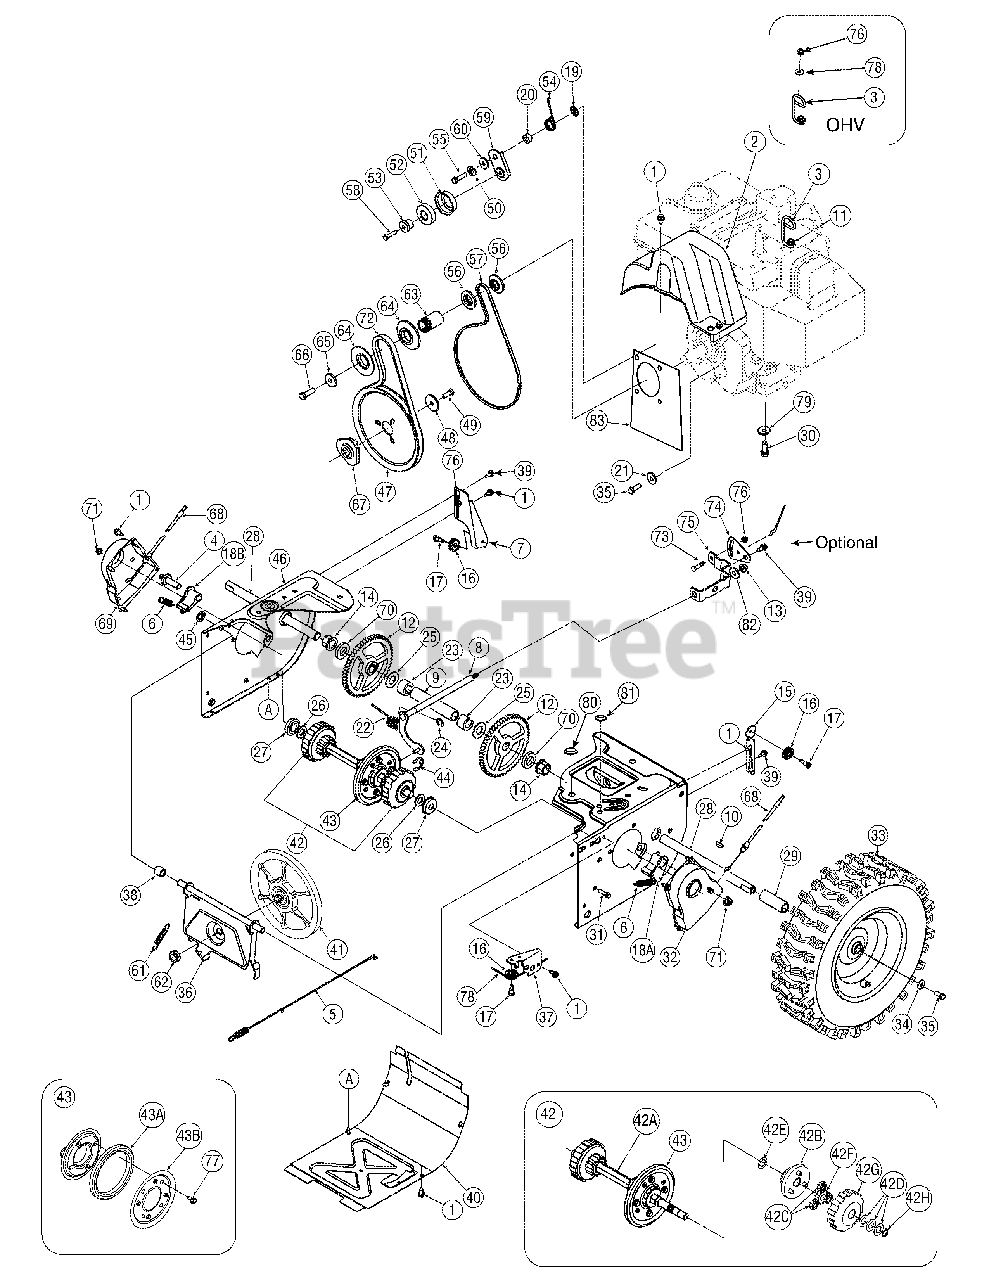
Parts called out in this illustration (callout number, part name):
1	Hex Wash Hd TT Scr. 1/4-20 x .625
2	Belt Cover ( w/4 Way Chute Control)
2	Belt Cover (Std.)
3	Cable Control Wire
4	Drive Shaft Actuator
5	Drive Clutch Cable 44.83'' Lg.
6	Extension Spring .5D x 1.71 Lg.
8	Shift Rod Assembly
9	Axle Support Tube
10	#9 Hi-Pro Key 3/16- x 3/4 Dia HT
11	Hex Wash Hd Tapp Screw 5/16-18 x 1.00
12	Gear, 56T
13	Flange Lock-Nut 5/16-18 Gr. F Nylon
14	Hex Flange Bearing .751'' ID
16	Cable Guide Roller
17	Hex Shld.Scr.1/4-28 x .375
18A	Dogg Assembly - LH
18B	Dogg Assembly - RH
19	Push Nut
20	Spacer .340 x .750 x .360" Lg.
21	Shoulder Spacer
22	Torsion Spring .750 ID x .968'' LG
23	Spacer .340 x .750 x .360" Lg.
24	Retaining Ring
25	Flat Washer .760 ID x 1.49 OD
26	Flat Washer .580 x 1.125 x .080
27	Ball Bearing
28	Axle Support Tube
29	Spacer .340 x .750 x .360" Lg.
30	Hex Wash HD Tap Scr 3/8-16 x .88
31	Hex Bolt 1/4-20 x 1.00
34	Cupped Washer .345 ID x .88 OD x .060
35	Hex L-Bolt 5/16-24 x .75 Gr 5
38	Spacer .513 ID x 1.0
39	Shoulder Screw .373 x .105:TT 1/4-20
41	Friction Wheel Disc Assembly
42	Drive Shaft Assembly
42A	Hex Drive Shaft(500)
42B	Planetary Carrier Assembly
42C	Gear 12T
42D	Flat Washer .58 x 1.12 x .02
42E	Flat Washer 5/8 ID x 1.0 OD
42F	Gear 18T
42G	Ring Planetary Gear Assembly(500)
42H	Retaining Ring 1.56 Dia
43	Friction Wheel Assembly
43A	Friction Wheel Rubber
43B	Friction Plate
44	Retainer Ring
45	Cap Speed Nut 1/4 Rod
47	Auger Pulley
48	Flat Washer .34 x 1.50 x .150
49	Hex Bolt 5/16-24 x 0.875
50	L-Wash 5/16 ID
51	Bearing Sleeve
52	Ball Bearing 20 x 47 x 14:6204:DS
53	Spacer .513 ID x 1.0
54	Torsion Spring .850ID x .354'' Lg
55	Hex HD Cap Scr. 5/16-24 x 1.25 Lg
56	Pulley Half
57	Belt 3/8 x 34.4'' Lg
58	Hex Bolt 1/4-20 x 1.25
59	Wheel Drive Idler Bracket
60	Shoulder Spacer
61	Extension Spring
62	Jam L-Nut 5/8-18 Gr. 5 Nylon
63	Spacer .875 ID x 1.185 OD
64	Pulley Half
65	Flat Washer .40 ID x 1.25 OD x .160
66	Hex Screw 3/8-24 x 1.25
67	Pulley Adapter
68	Steering Cable
70	Axle Spacer
71	Flange Lock - Nut 3/8-16 Gr F Nylon
72	Belt .5 x 35.0'' Lg
73	Hex Bolt 1/4-20 x .62 Gr. 5
76	Flange Lock-Nut 1/4-20 Gr. F Nylon
77	Hex Wash Hd. TT Scr. 1/4-14 x .625
78	Flat Washer .28 ID x .74 DE x .063
79	Flat Washer .38 x 1.38 x .125
80	Plug 1/2''
81	Plug 3/8''
82	Flat Washer .469 x .875 x .105
84	Auger Clutch Cable 47.23'' Lg
